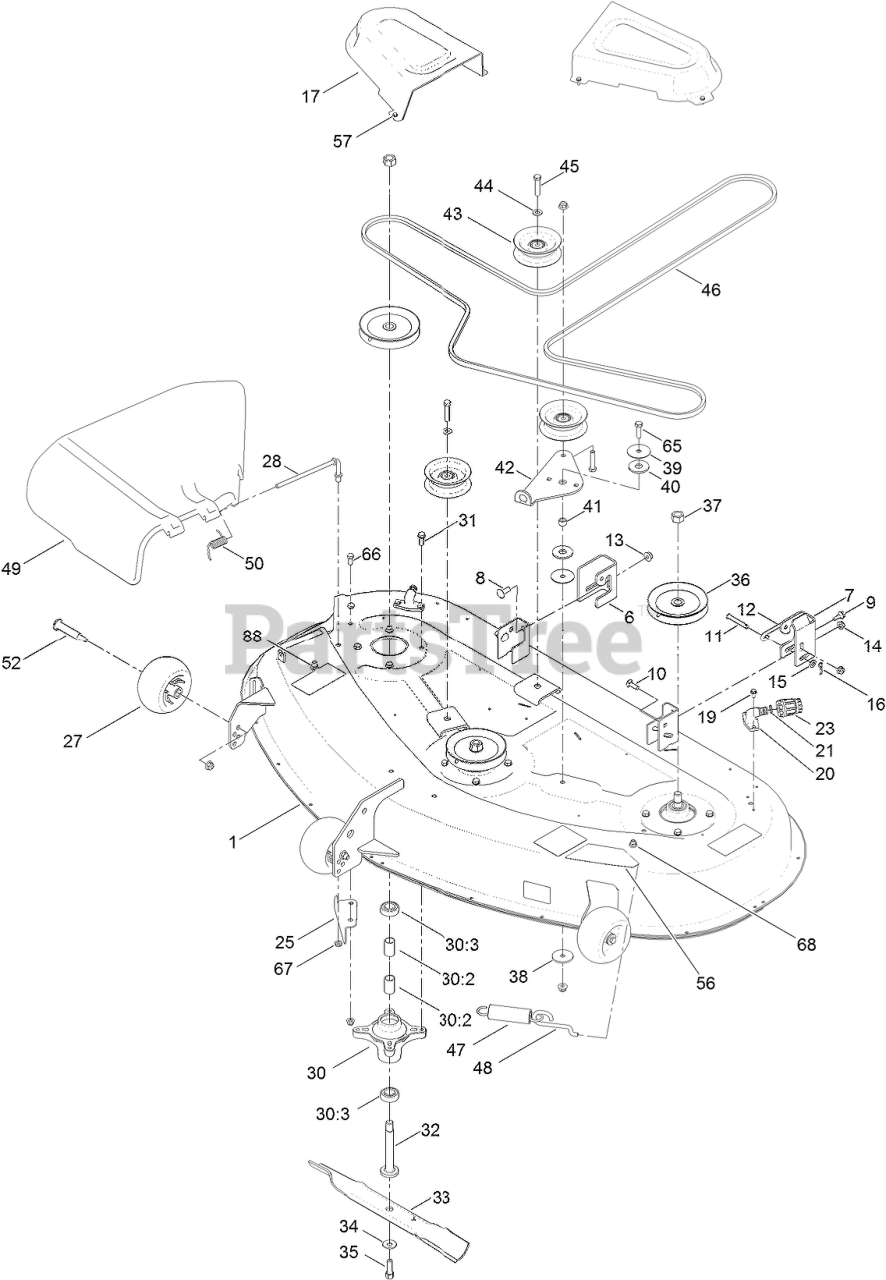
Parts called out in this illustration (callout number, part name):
1	54 INCH DECK ASM
6	BRACKET-HANGER, RH
7	BRACKET-HANGER, LH
8	BOLT-CARR
9	SCREW-SHOULDER, HHF
10	SCREW-CARR
11	PIN-CLEVIS
12	ROD-LEVEL, DECK
13	NUT-HF, NI
14	NUT-HF, NI
15	WASHER-PLAIN
16	PIN-COTTER
17	COVER-BELT
19	SCREW-HWH
20	FITTING-WASHOUT
21	O-RING
23	CONNECTOR-HOSE
25	BAFFLE-CUTOFF
27	ROLLER-SCALP, ANTI
28	ROD-PIVOT
30	SPINDLE ASM
30:2	SPACER
30:3	BEARING-BALL
31	SCREW-TAPTITE
32	SHAFT-SPINDLE
33	BLADE-HI LIFT, 18.75 INCH
34	WASHER-BELLEVILLE
35	SCREW-HH
36	PULLEY ASM
37	NUT-HEX
38	WASHER-REBOUND
39	WASHER
40	WASHER-FRICTION, COMPOSITE
41	SPACER
42	ARM-IDLER
43	PULLEY-IDLER, FLAT
44	WASHER-FLAT
45	SCREW-HH
46	BELT-V
47	SPRING-EXTENSION
48	HOOK-RETURN, SPRING
49	DEFLECTOR
50	SPRING-TORSION
52	BOLT-SHOULDER
56	DECAL-DECK
57	SCREW-TAPTITE
65	SCREW-HH
66	SCREW-HH
67	NUT-LOCK, NI
68	SCREW-HH
88	SCREW-CARR
